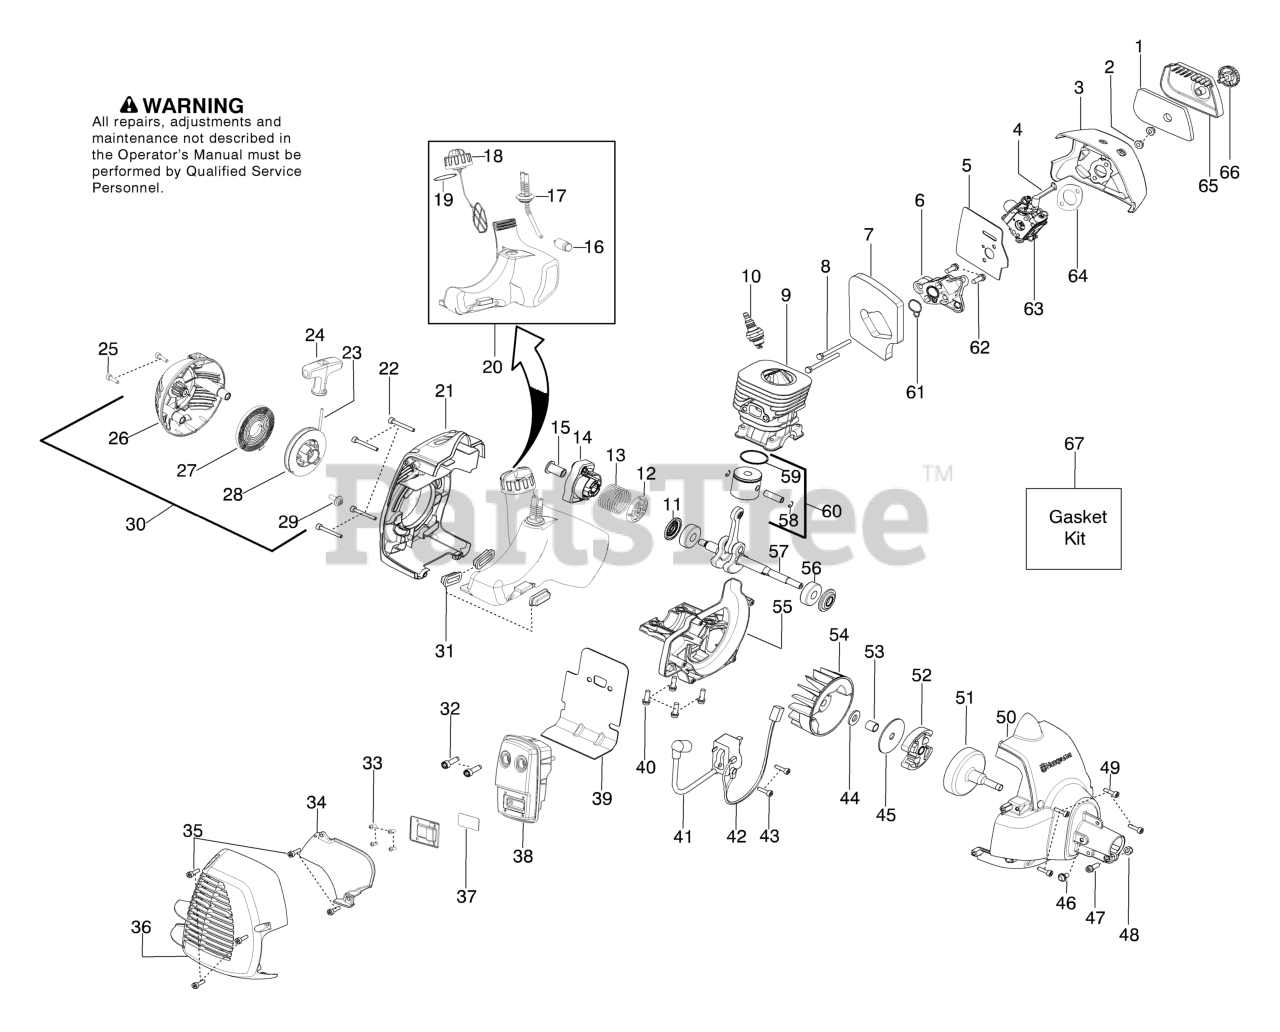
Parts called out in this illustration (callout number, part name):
1	FILTER AIRBOX
3	AIRBOX
4	CHOKE LEVER
5	KIT GASKET CARB
6	CARB ADAPTOR
7	KIT GASKET 28CC TRIMMER
8	BOLT CARB ADAPTOR
9	CYLINDER
10	Plug-Spark (RCJ-8Y)
11	KIT SEAL CRANKSHAFT
12	WASHER STARTER
13	SPRING STARTER CUP
14	ASSY STARTER CUP
15	COUPLING STARTER
16	FUEL PICK-UP ASSY
17	KIT FUEL LINE
18	ASSY-CAP W/RETAINER
19	O RING NITRILE
20	ASSY FUEL TANK
21	REAR SHROUD
24	STARTER HANDLE GRAY
25	SCREW M5-0.8X30MM
26	STARTER HOUSING
27	%KIT STARTER SPRING
28	KIT STARTER PULLEY
30	STARTER HOUSING ASSY
31	ISOLATOR FUEL TANK
32	BOLT MUFFLER
33	SCREW-10-16 X 1/2 HI-LO
34	SHIELD HEAT
35	SCREW M4 X 1.75 PT 16MM
36	MUFFLER GUARD
37	KIT SPARK ARRESTOR SCREEN
38	ASSY MUFFLER
39	GASKET PAPER METAL
40	SCREW-M5-0.8 X 25MM(TAP)
41	IGNITION MODULE MBU-7
42	ASSY MODULE LEAD WIRE
43	SCREW M4 X .70 TT 16MM
45	WASHER-CLUTCH
48	NUT HEX LOCK 10-24
49	SCREW M4 X .70 TT 16MM
50	FAN HSG ASSY
51	ASSY-CLUTCH DRUM
52	%KIT CLUTCH ASSY
53	SPACER FLYWHEEL
55	CRANKCASE CASTING
56	BEARING RADIAL BALL (6201)
57	KIT CRANKSHAFT ASSY
58	WRIST PIN RET.
59	RING PISTON
60	KIT PISTON 28CC TRIMMER
61	KIT GASKET 28CC TRIMMER
62	SCREW-M5-0.8 X 25MM(TAP)
63	KIT CARBURETOR
64	KIT GASKET 28CC TRIMMER
65	COVER-AIR BOX
66	KNOB ASSY AIRBOX COVER
67	KIT GASKET 28CC TRIMMER
